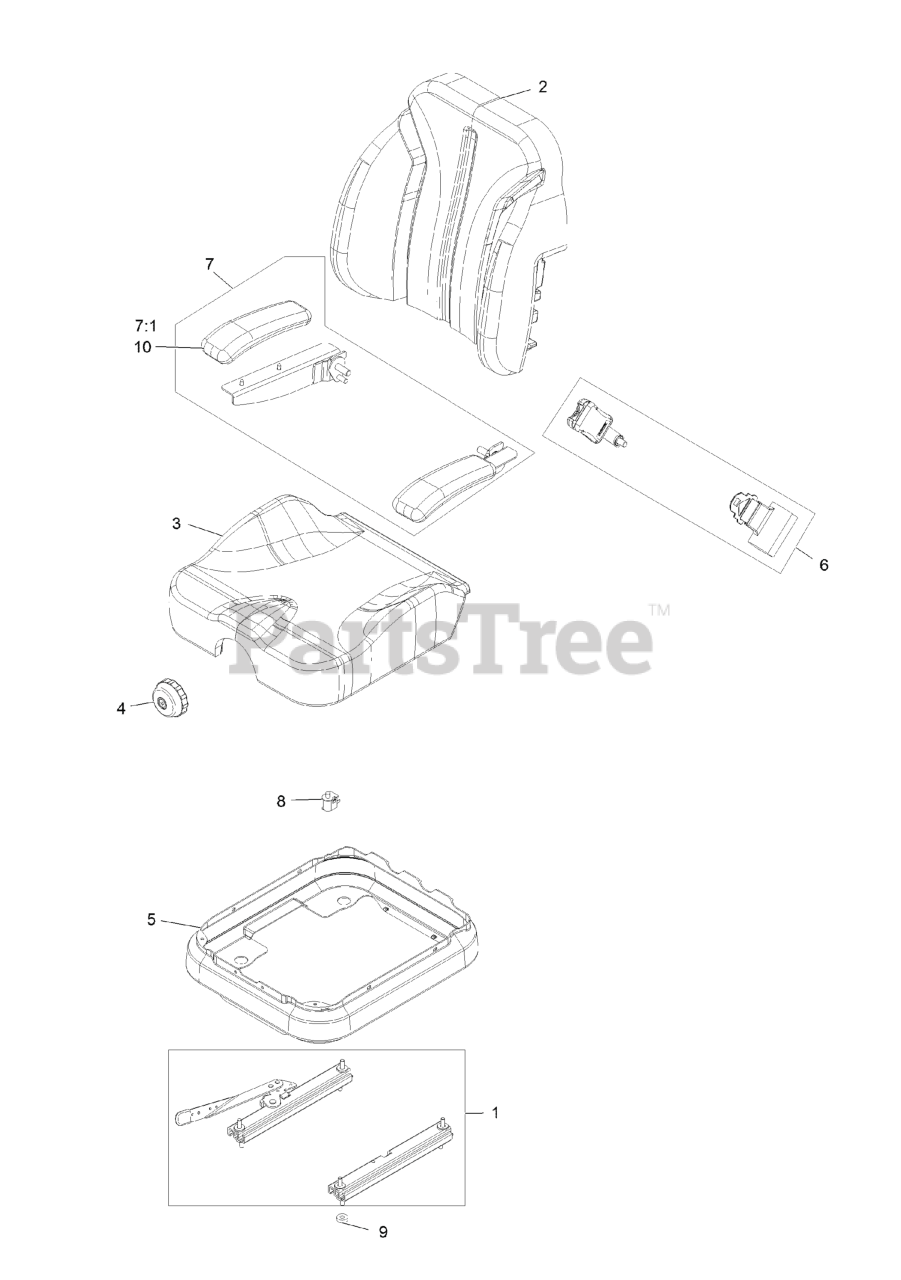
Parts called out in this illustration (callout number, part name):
1	TRACKS-4" TRAVEL
2	COVER-SEAT BACK SVC
3	COVER-SEAT BOTTOM SVC
4	KNOB-ADJUSTER
5	BELLOWS-SEAT
6	KIT-SEAT BELT
7	ARMREST KIT
7:1	CUSHION-REST, ARM
8	SWITCH-BAIL
10	CUSHION-REST, ARM
